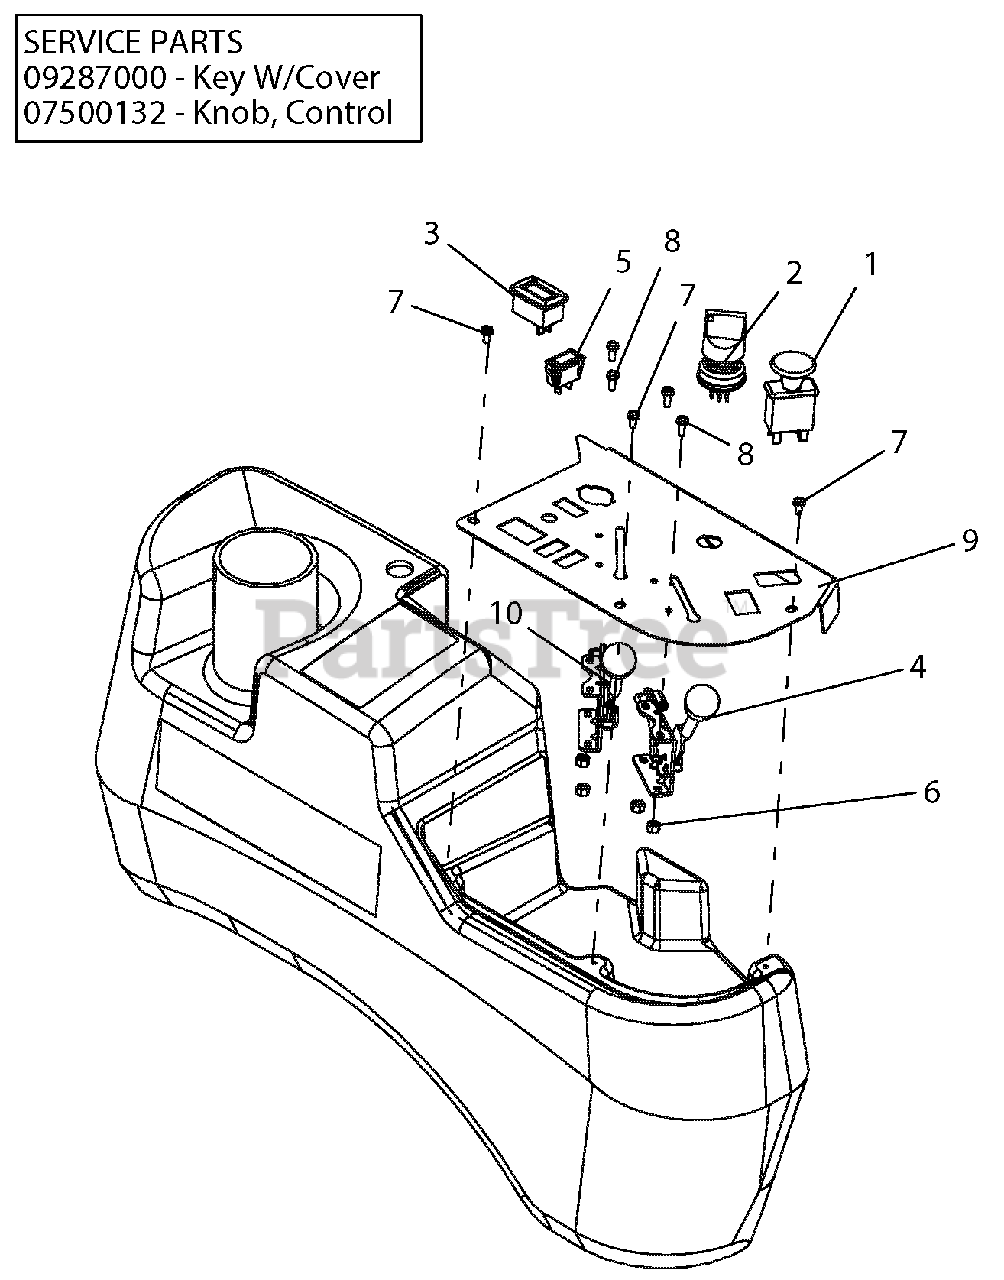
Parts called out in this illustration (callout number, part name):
1	SWITCH, CLUTCH
2	SWITCH, IGNITION
3	METER, HOUR W/MAINTENANCE
4	CABLE, PRO-CONTROL THROTTLE
5	LIGHT, INDICATOR
6	NUT-LK-NYL #10-24 YWZC
7	SCR-MCH 10-24X.38 HWHSTAINLESS
8	@SCR-MCH 10-24X.50 HWH YWZC
9	PANEL, CONTROL (BLACK)
10	CABLE, PRO-CONTROL THROTTLE
